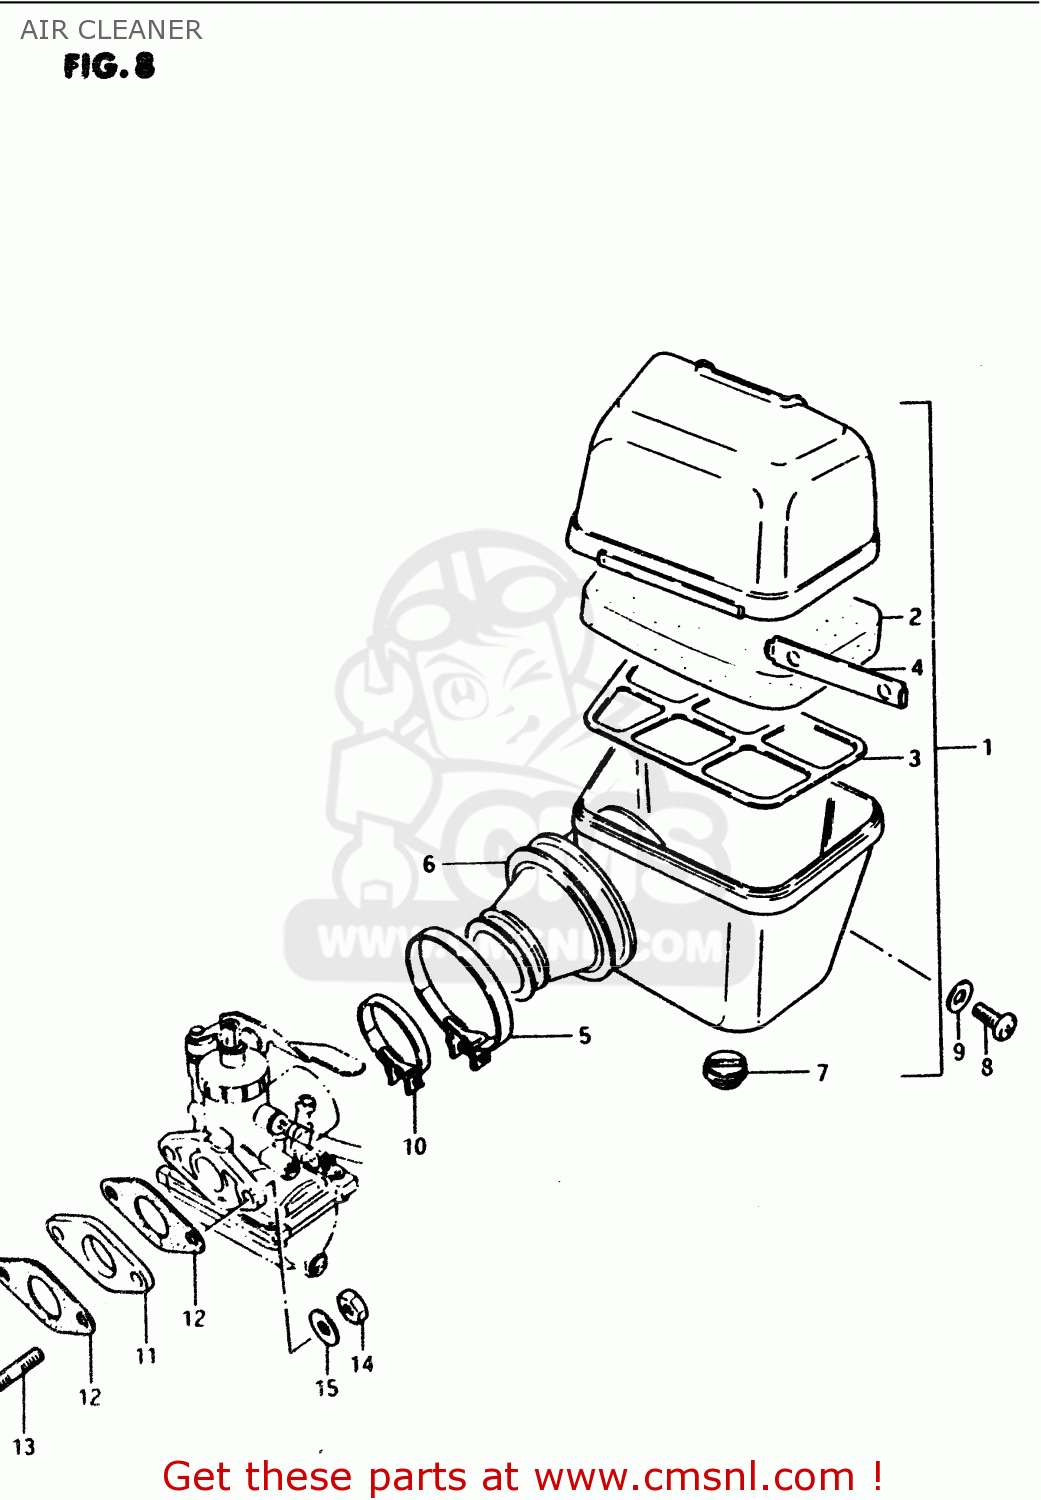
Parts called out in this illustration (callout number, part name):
1	CLEANER ASSY, AIR
2	FILTER
3	HOLDER
4	SLIDER
5	CLAMP
6	TUBE,OUTLET
7	CAP,DRAIN
8	SCREW
9	WASHER
10	CLAMP
11	INSULATOR,CARBURETOR
12	GASKET,CARBURETOR (MCA)
13	STUD BOLT
14	NUT
15	WASHER
